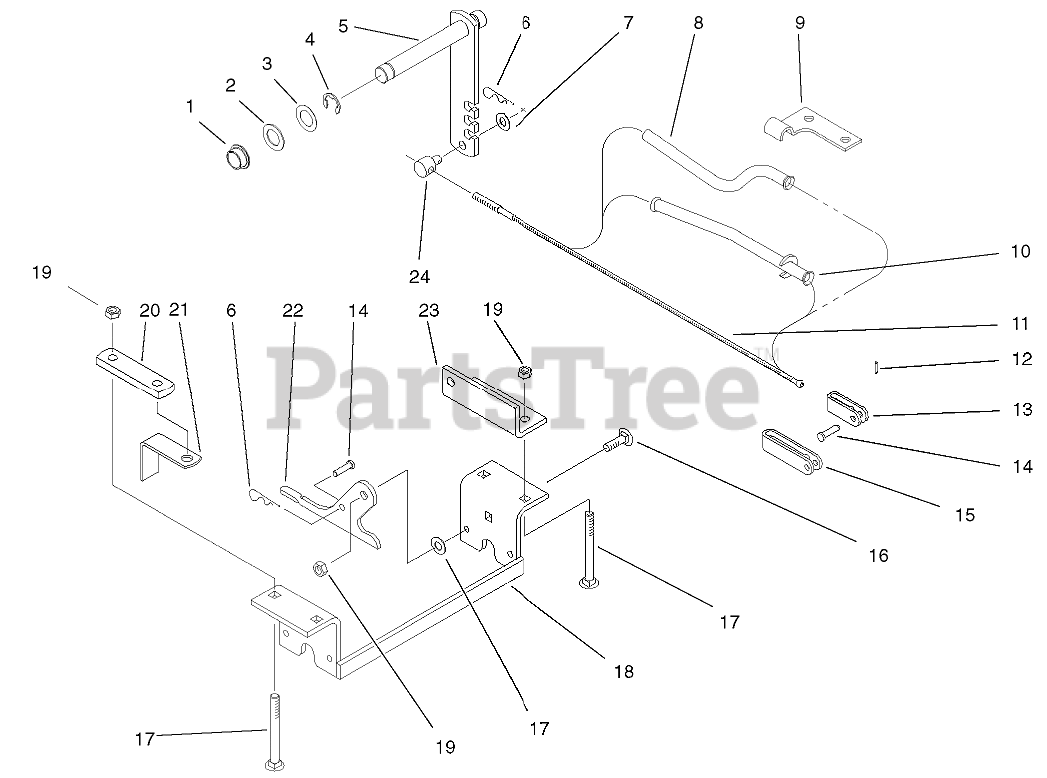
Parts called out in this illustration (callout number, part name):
1	BUSHING-BRONZE
2	WASHER
3	WASHER-SHIM
4	E-RING
5	Lever ASM
6	PIN-HAIR
7	WASHER-FLAT
8	Tube-Conduit, 8 Speed
9	Clamp-Conduit
10	Conduit Tube ASM
11	CABLE
12	PIN-COTTER
13	CLEVIS-SHORT
14	PIN-CLEVIS
15	CLEVIS-LONG
16	BOLT-CARR
17	SCREW-CARR
18	BRACKET-AXLE
19	NUT-HEX
20	BRACKET-REAR LINK MOUNTING
21	SPACER-BRACKET
22	PLATE-LATCHING
23	Link-Bracket
24	TRUNNION-CLUTCH ROD
